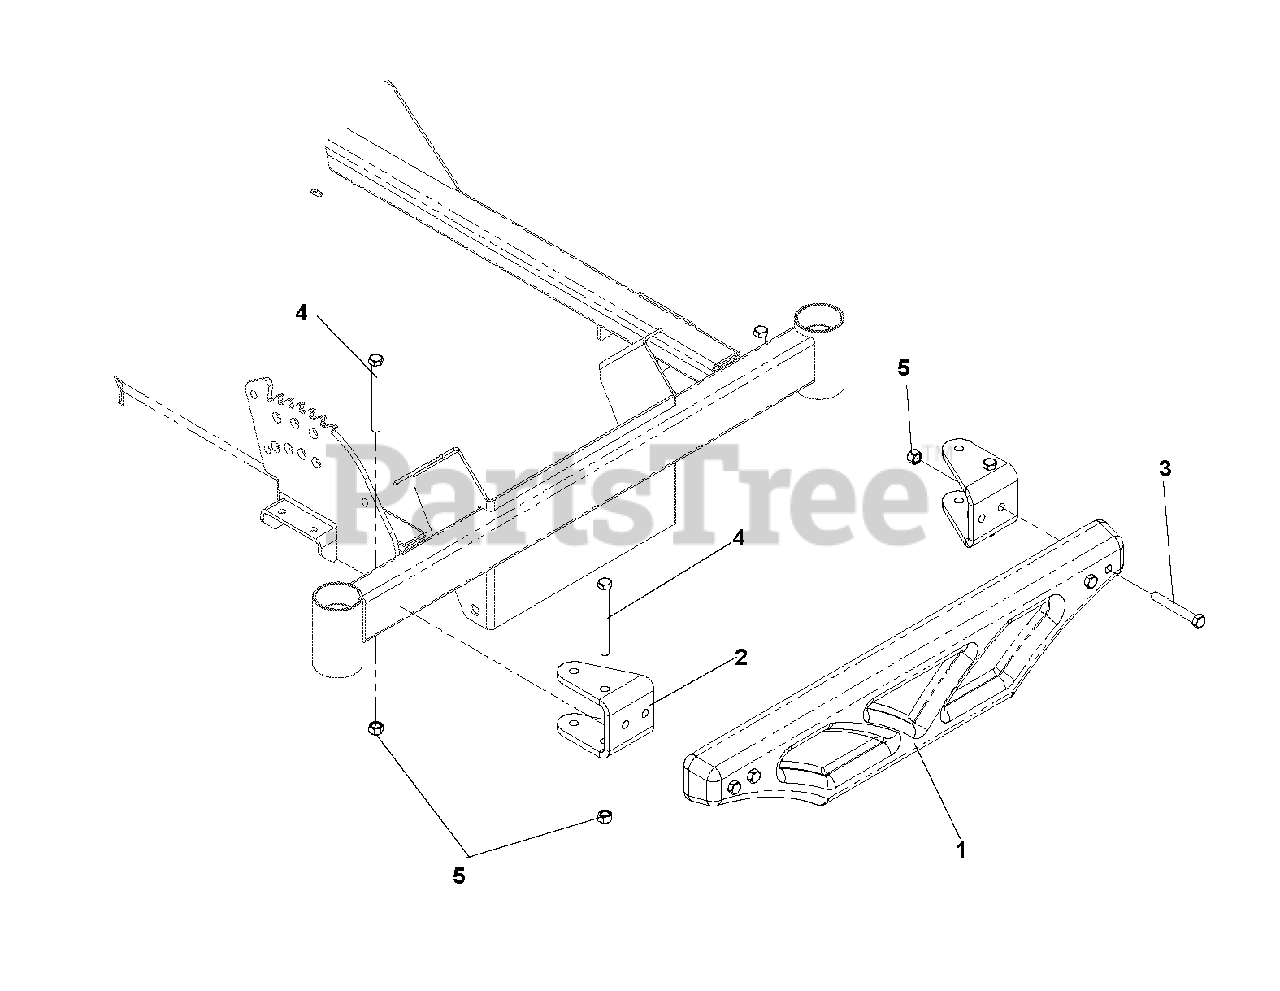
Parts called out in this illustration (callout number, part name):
1	CAST WEIGHT
2	BRACKET, WEIGHT
3	HEX SCREW 3/8-20 X 2.75
4	HCS3/8-16.X
5	NUT 3/8-16 NYLOC
